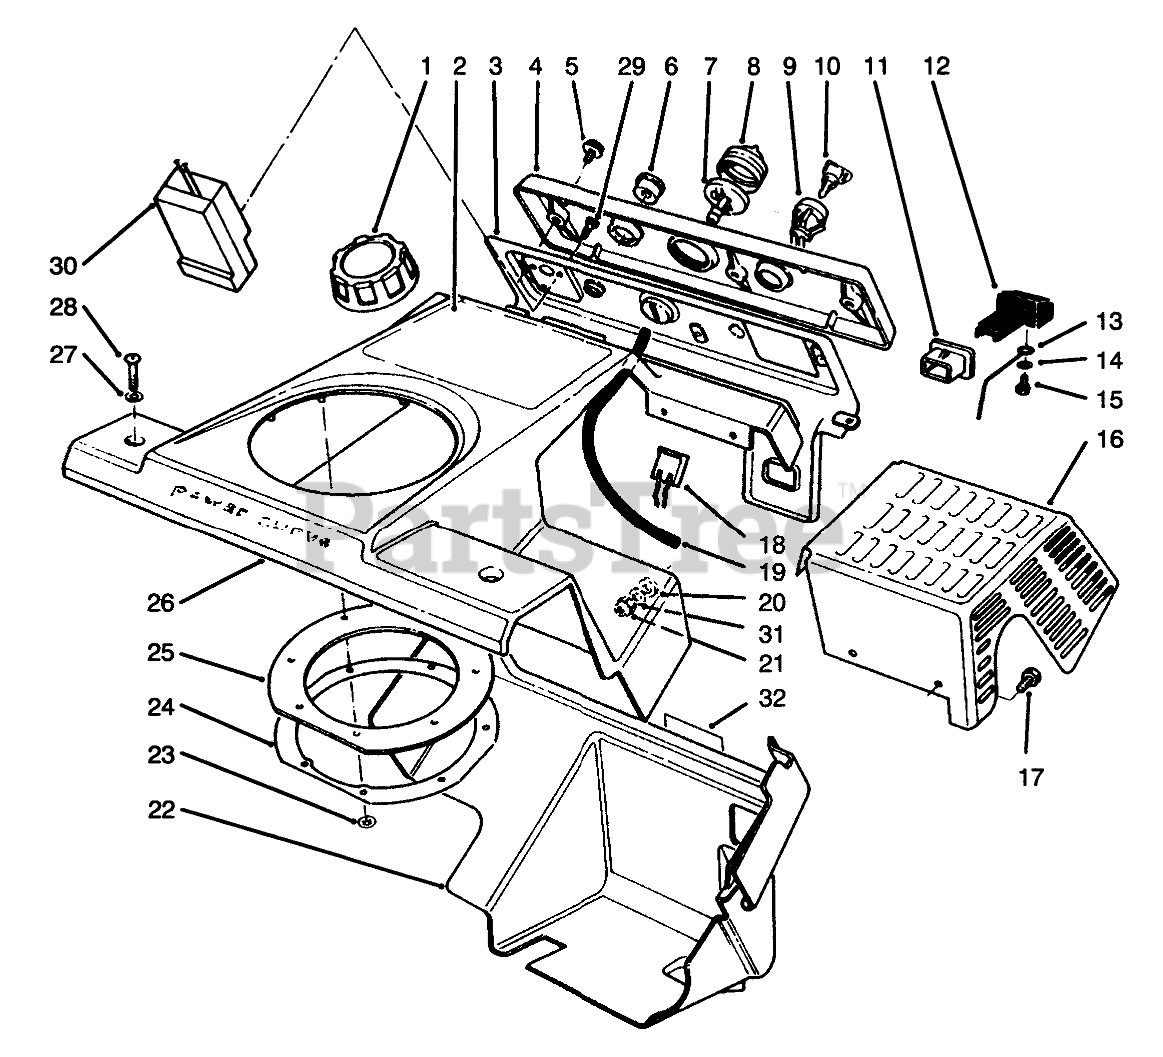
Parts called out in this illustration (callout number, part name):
1	CAP-FUEL ASM
2	DECAL - CCR 2000E
3	Panel-Control (Incl. Ref. #6-8 & 11)
4	Plate-Name
5	SCREW-HWH
6	GUIDE-ROPE, STARTER
7	BODY-PRIMER
8	BULB-PRIMER
9	SWITCH
10	KEY-IGNITION
11	FITTING
12	CONTROL-CHOKE
13	Unkage-Choke
14	WASHER-PLAIN
15	SCREW-PPH
16	Wa-Shield
17	SCREW-SHH
18	CONNECTOR-BODY
19	PRIMER HOSE
20	WASHER
21	NUT-LOCK, NI
22	LOWER SHROUD
23	PALNUT
24	Retainer-Chute Seal
25	SEAL-CHUTE
26	Upper Shroud Assembly (Incl. Ref. #2 & 23-25)
27	WASHER-FLAT
28	SCREW-PPH
29	SCREW-PLASTITE
30	Switch Assembly
31	WASHER-FLAT
32	DECAL - WARNING
